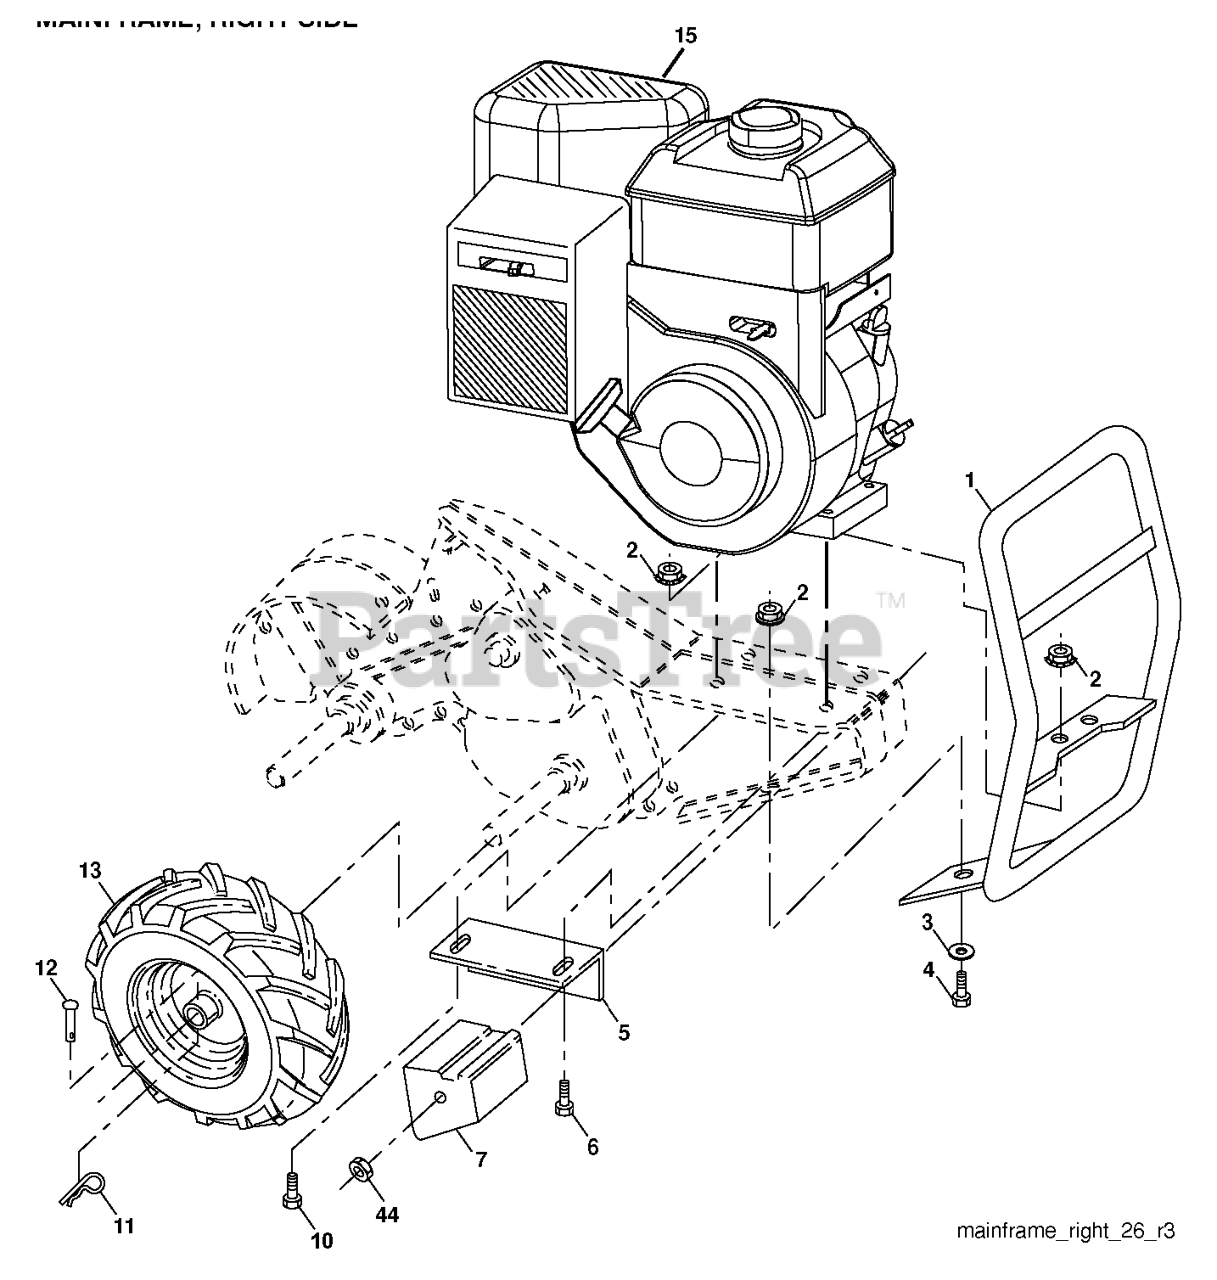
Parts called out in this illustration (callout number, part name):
1	BUMPER.ASM.REAR.TILLER.479
2	LOCKNUT-FLANGE 5/16-18
3	WASHER
4	BOLT
5	BRACKET.REINFORCEMENT.RH.BLACK
6	BOLT, HEX 5/16-18X1-3/4
7	COUNTERWEIGHT.RH
10	BOLT
11	RETAINER M
12	RIVET
13	WHEEL.ASM.DRT.13X5-6.RT.SILVER
